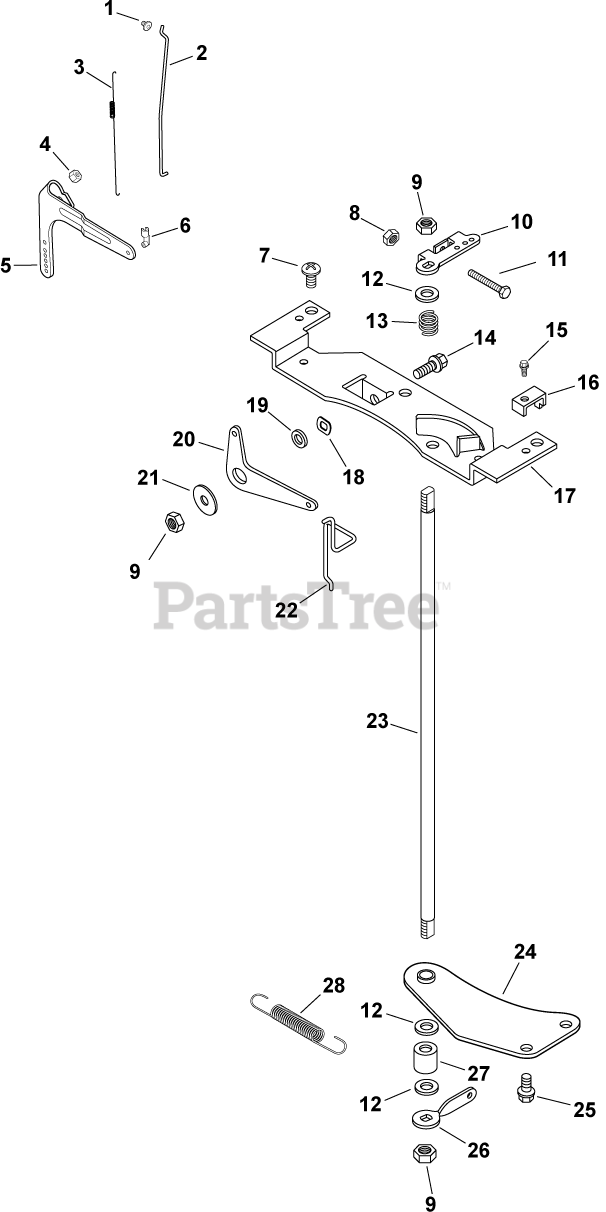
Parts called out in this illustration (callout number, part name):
1	BUSHING, LINKAGE RETAINING
2	LINKAGE, THROTTLE
3	SPRING, LINKAGE
4	NUT, FLG M6X1.0
5	LEVER, GOVERNOR-USE 24 090 57-S
6	BUSHING, THROTTLE LINKAGE
7	SCREW, PHL HD 11-16X3/4"
8	NUT, M4X0.7
9	NUT, LOCK M6X1.0
10	LEVER, THROTTLE CONTROL
11	SCREW, CAP M4X.7X30
12	WASHER, FLAT 1/4"
13	SPRING, THROTTLE SHAFT
14	SCREW, FLG M6X1.0X16
15	SCREW,FLG THD FRM M5X0.8X16-(#25086398S)
16	CLAMP, CABLE
17	BRACKET, CONTROL-USE 24 126 219-S
18	WASHER, SPRING 3/8"
20	LEVER, CHOKE
21	WASHER, FLAT 1/4"
22	LINKAGE, CHOKE
23	SHAFT, THROTTLE
24	BRACKET, THROTTLE SHAFT
25	SCREW,FLG THD FRM M6X1.0X16-(#25086397S)
26	LEVER, THROTTLE CONTROL
28	SPRING, GOVERNOR (BLACK)
